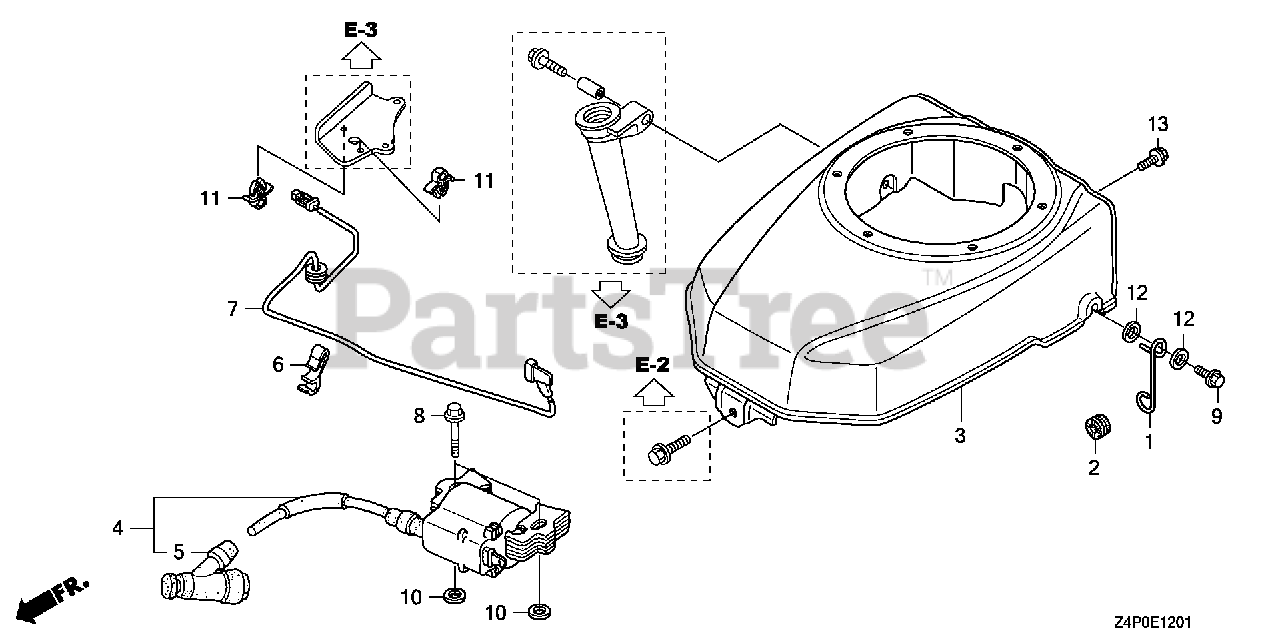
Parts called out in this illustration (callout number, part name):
1	STAY, FUEL TUBE
2	RUBBER, RADIATOR MOUNTING
3	COVER, FAN *NH1* (BLACK)
3	COVER, FAN *R280* (POWER RED)
4	COIL ASSY., IGNITION
5	CAP ASSY., NOISE SUPPRESSOR
6	CLAMP, WIRE
7	WIRE, STOP SWITCH
8	BOLT, FLANGE (6X28) (CT200)
9	BOLT, FLANGE (6X16) (CT200)
10	WASHER, PLAIN (6MM)
11	CLIP A, CABLE (3.8MM BLACK) (NIFCO)
12	WASHER, PLAIN (6MM)
13	BOLT, FLANGE (6X12)
